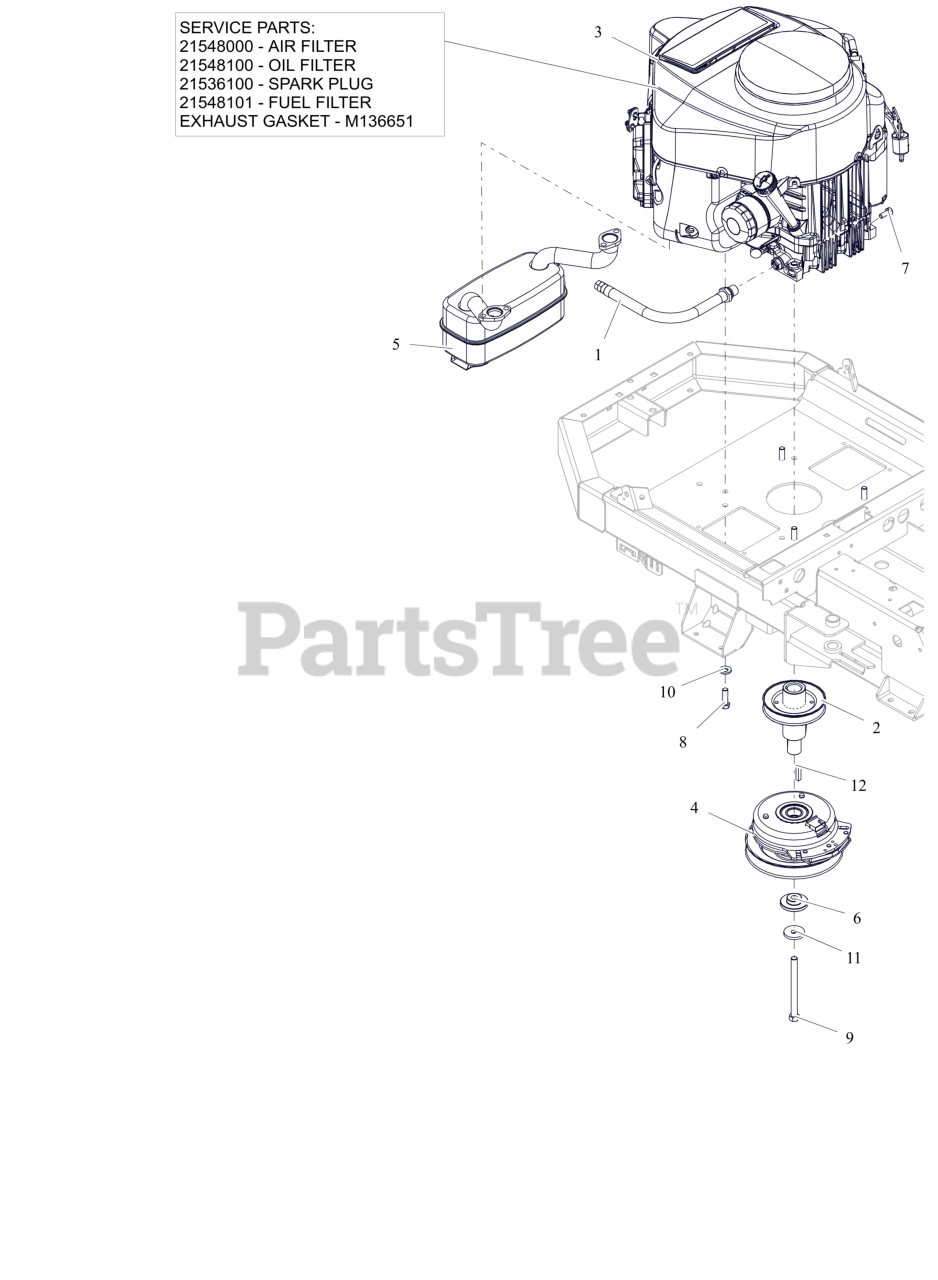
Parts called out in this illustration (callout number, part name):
1	HOSE, OIL DRAIN
2	WLDMT, DRIVE SHEAVE (LONG)
3	ENGINE, KAWASAKI FR651 21.5HP
3	AIR FILTER, KAWASAKI FR
3	OIL FILTER, KAWASAKI FR
3	PLUG, SPARK
3	FUEL FILTER-KAWASAKI FR
3	GASKET, MUFFLER #
4	CLUTCH,105FTLB MONOPOLE 6.83"
5	MUFFLER - KAWASAKI
6	BSHG-FLG .469X1.06X.574X2.0
7	BLT, HEX M8-1.25X20 G8.8 ZCC
8	BLT, HEX .38-16X1.25 G5 ZCC NT
9	BLT, HEX .44-20X5.00 G8 ZCC NT
10	WASHER, 3/8" SPRING DISC
11	WASHER, 7/16" SPRING DISK
12	KEY-SQ .25 X 1.25 X .25 SAE
